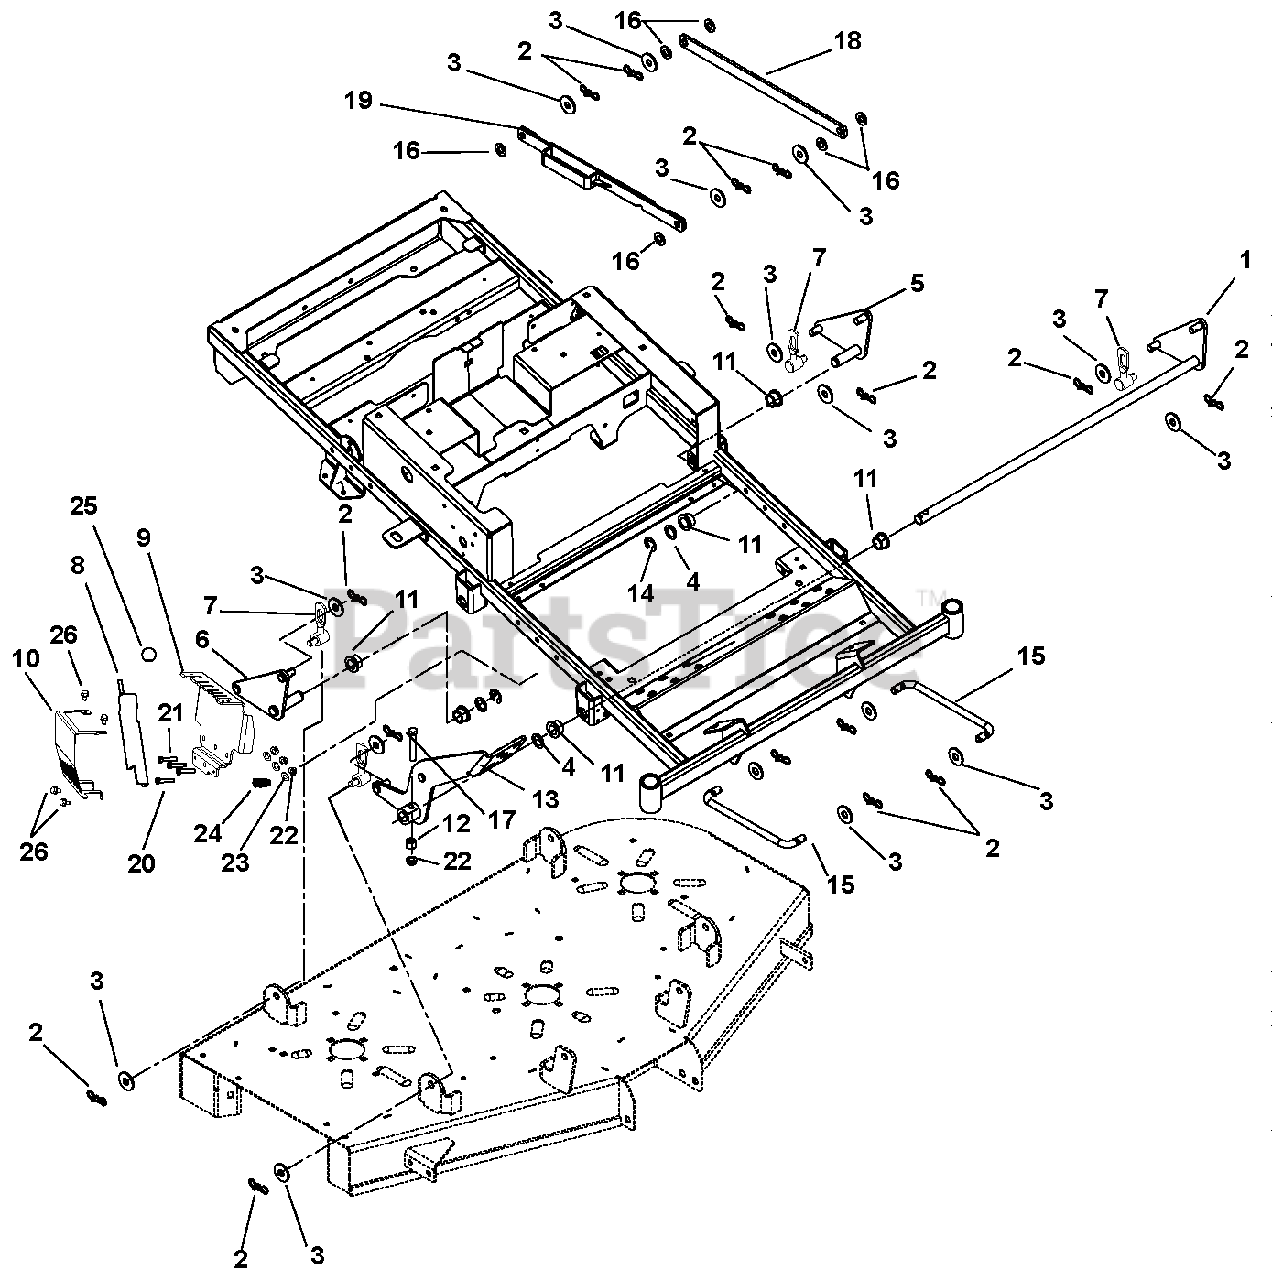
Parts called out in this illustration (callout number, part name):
1	Weldment, Deck Pivot
2	Pin, Bow Tie Locking Cotter .091 x 1.875
3	Washer, Flat Steel.511 x 1.441 x .125
4	Washer, Flat Steel .754 x 1.125 x .062
5	Weldment, Deck Pivot ZTXL Rear Left Hand
6	Weldment, Deck Pivot ZTXL Rear Right Hand
7	Assembly, Deck Link
8	Lever, Weldment
9	Bracket, HOC XL
10	Guard, Plate Styled HOC
11	Bushing, Flange .750 x 1.000 x .625 x 1.250
12	Bushing, Sleeve .391 x .688 x .52
13	Weldment, XL Foot Pedal
14	Ring, Retaining-External .750 x .050
15	Link, Drag
16	Washer, Flat Nylon .52 x 1.00 x .08
17	Bolt, Hex .38-16 x 2.50 Grade 5
18	Link, Lift
19	HOC, Link Retaining XL
20	Bolt, Hex .38-16 x 2.25
21	Bolt, Hex .38-16 x 1.75 Grade 5
22	Nut .38-16 Nyloc Flange
23	Washer, Flat Steel .38 x .875 x .083
26	Screw, Tapping Hex Washer Head Thread Rolling .25-20 x .50 YWZ
